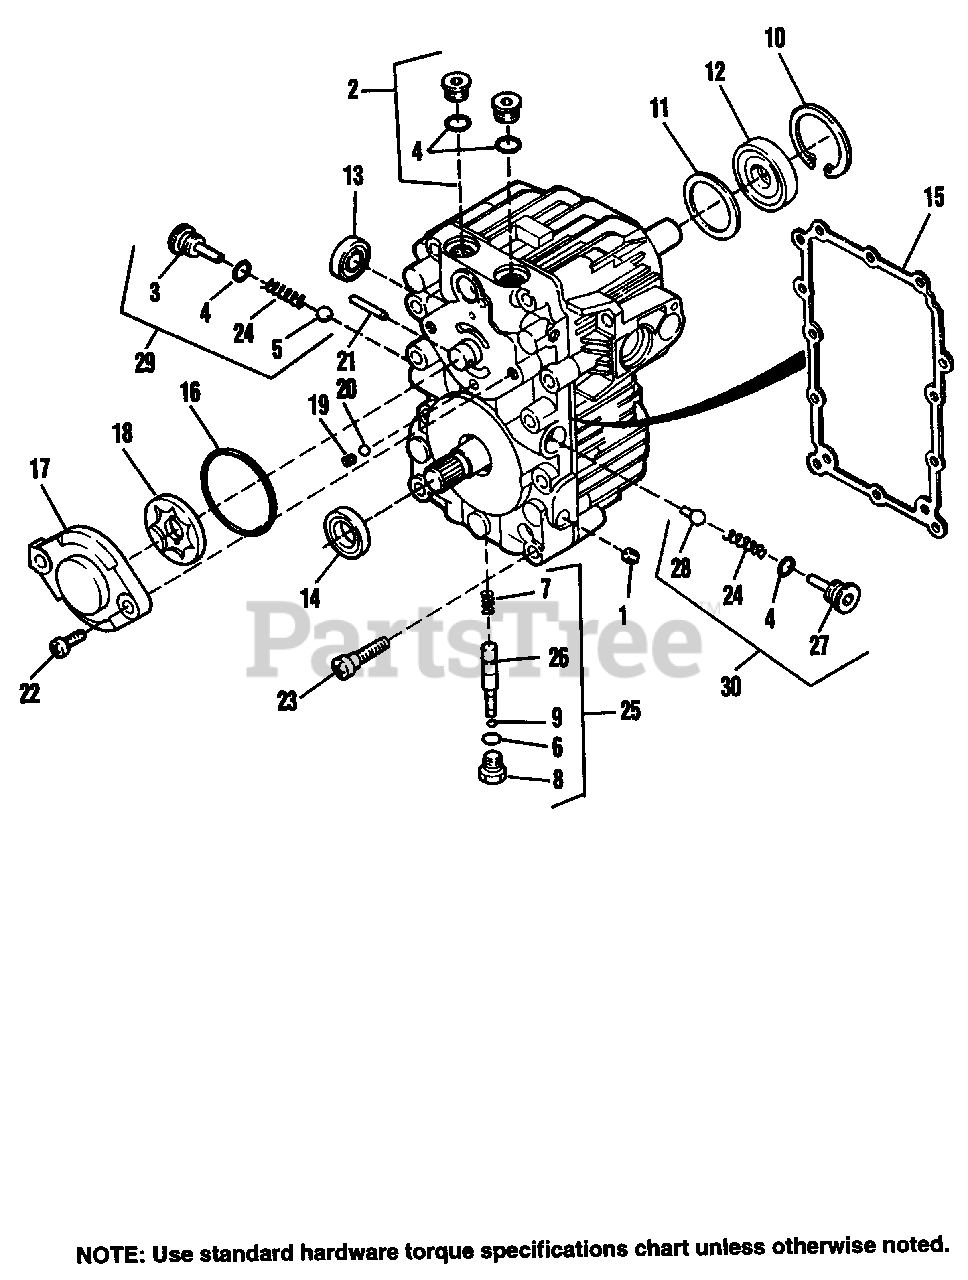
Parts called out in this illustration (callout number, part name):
2	Plug, w/O-Ring
3	Check valve plug
4	O-ring, Rubber
6	O-ring, Rubber
8	By-pass PLUG
9	O-RING
10	Retaining ring
11	Spacer
12	Seal
13	Seal
14	Lip seal
15	Gasket, Center Section
16	O-ring, Rubber
17	Charge pump housing
18	Gerotor assy.
22	Screw, M8 x 20
23	Screw, M8 x 35
24	SPRING
25	By-pass valve kit (Incl. Ref. Nos. 6-9 & 26)
26	By-pass spool
28	POPPET, Orifice
29	Check valve kit (Incl. Ref. Nos. 3-5 & 24)
30	CHECK VALVE KIT, Poppet (Incl. Ref. Nos. 4, 24, 27 & 28)
